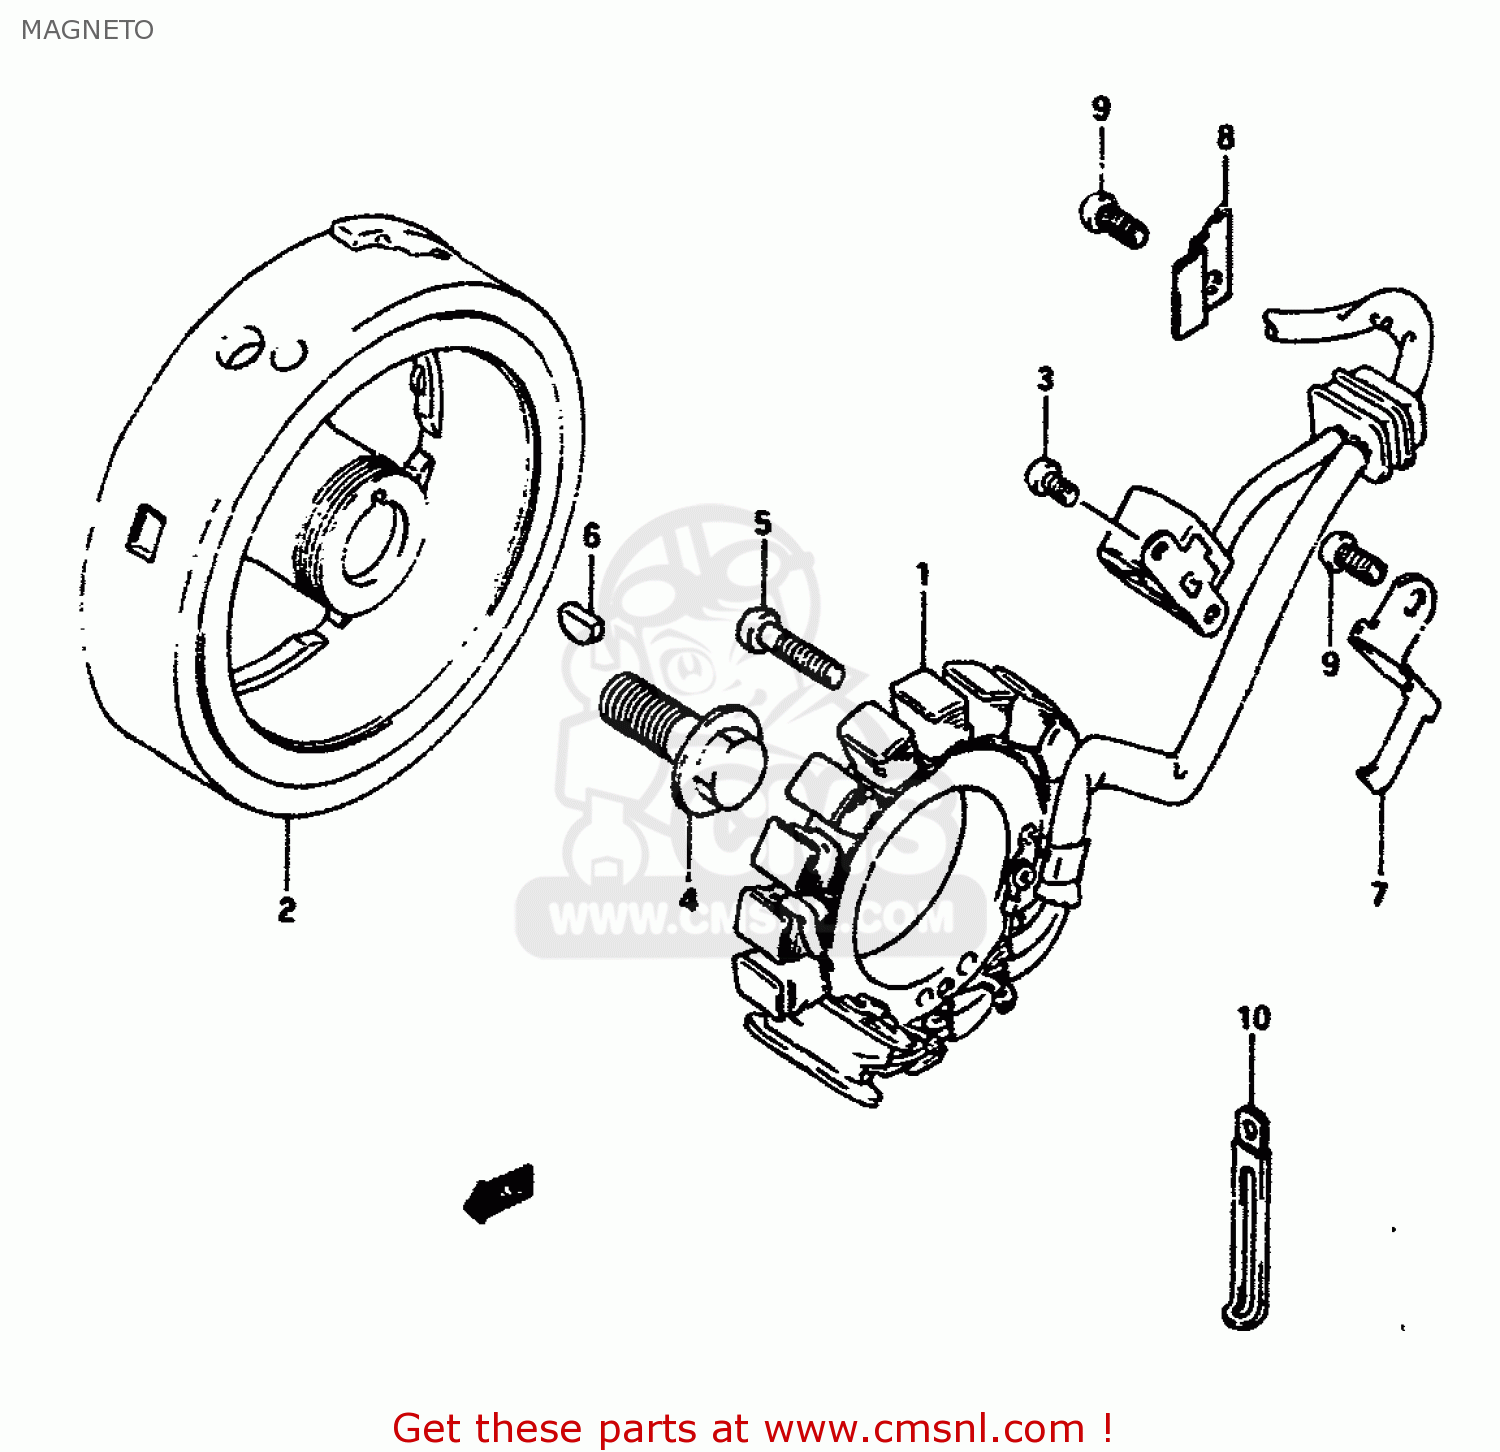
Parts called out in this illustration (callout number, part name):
1	STARTER ASSY
2	ROTOR
3	SCREW
4	BOLT(14X43)
5	SCREW
6	KEY 4MM
7	CLAMP,MAGNETO LEAD WIRE
8	CLAMP,MAGNETO LEAD WIRE
9	SCREW
10	CLAMP
